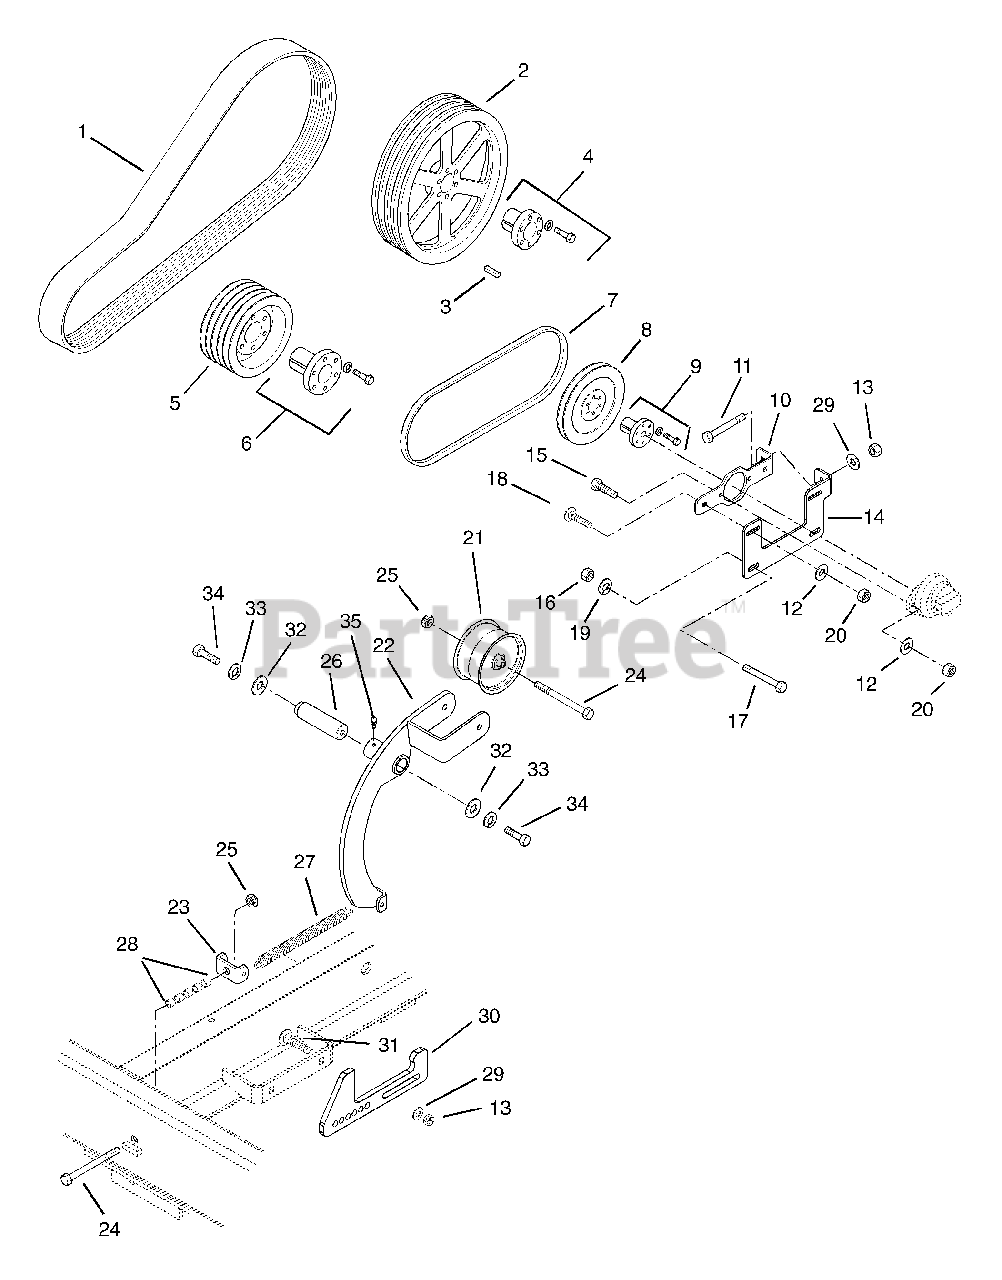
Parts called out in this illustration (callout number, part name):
1	V-Belt-4 Groove Banded
2	Pulley Driven 16 in
3	Key-Straight .50 x .50 x 1.75
4	Bushing-Sheave
5	Drive Sheave
6	Bushing-Sheave
6	Bushing-2.250 Bore w/.625 Key
8	Pump Sheave
9	Bushing-Sheave
10	Hydraulic Pump Bracket
11	Bolt-Hex .375-16 x 3.00 Grade 5
12	Washer-Flat-Steel .438 x 1.25 x .083
13	Nut-Locking-Center .38-16
14	Hydraulic Pump Mount Bracket
15	Bolt-Hex .44-14 x 1.25 Grade 5
16	Nut-Locking-Center .50-13
17	Bolt-Hex .50-13 x 3.00 Grade 5
18	Bolt-Round Head Square Neck .44-14 x 1.50
19	Washer-Flat-Steel .563 x 1.38 x .109
20	Nut-Locking-Center .44-14
21	Pulley-Idler
22	Idler Arm Weldment
23	Spring Bracket
24	Bolt-Hex .50-13 x 6.00 Grade 5
25	Nut-Locking .50-13
26	Shaft-Idler Arm Pivot
27	Spring-Tension .156 x 1.062 x 2.68
28	Spacer-Idler Spring
29	Washer-Flat-Steel .438 x 1.00 x .083
30	Stop-Idler Arm
31	Bolt-Round Head Square Neck .38-16 x 1.25 Grade 2
32	Washer-Flat-Steel .812 x 1.5 x .135
33	Washer-Locking .75 x .188
34	Bolt-Hex .75-10 x 1.50 Grade 5
35	Fitting-Lube
